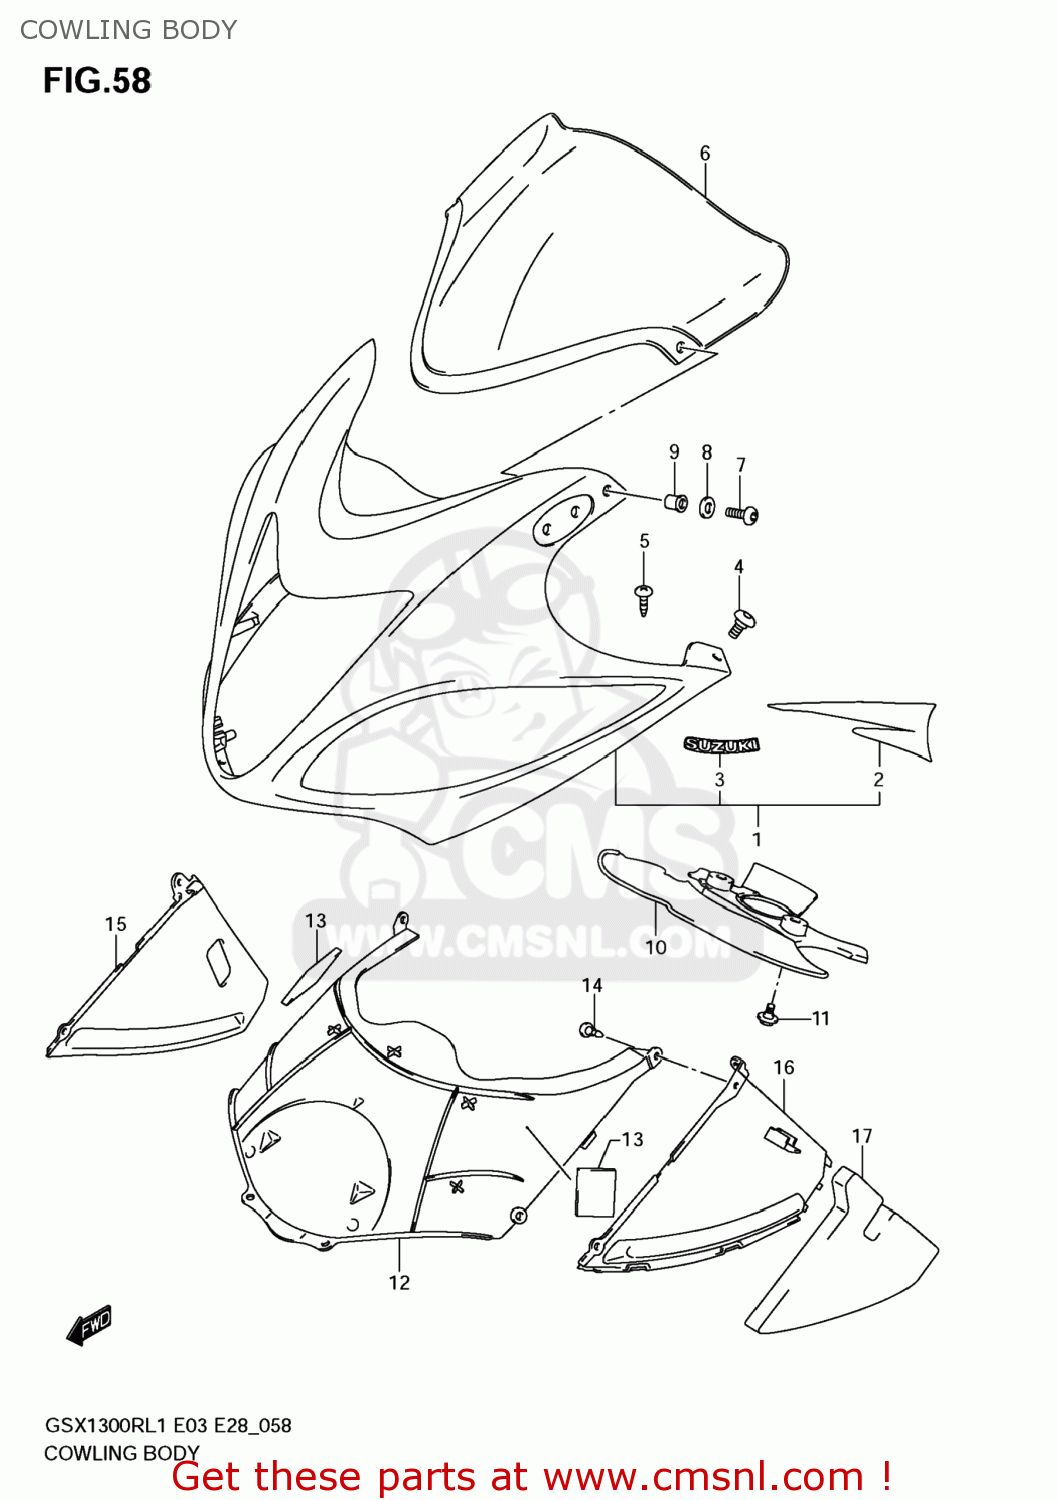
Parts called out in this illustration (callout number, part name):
1	COWLING ASSY,BODY
2	TAPE SET,BODY COWL
3	EMBLEM
4	SCREW(5X16)
5	SCREW(5X16)
6	WINDSCREEN
7	SCREW(5X14)
8	WASHER
9	NUT
10	COVER,LWR BRACKET
11	BOLT(6X12)
12	COVER,BODY COW
13	COVER
14	CLIP(BLACK)
15	COWLING,UNDER INNER,R
16	COWLING,UNDER INNER,L
17	CUSHION,INNER COWL,L
